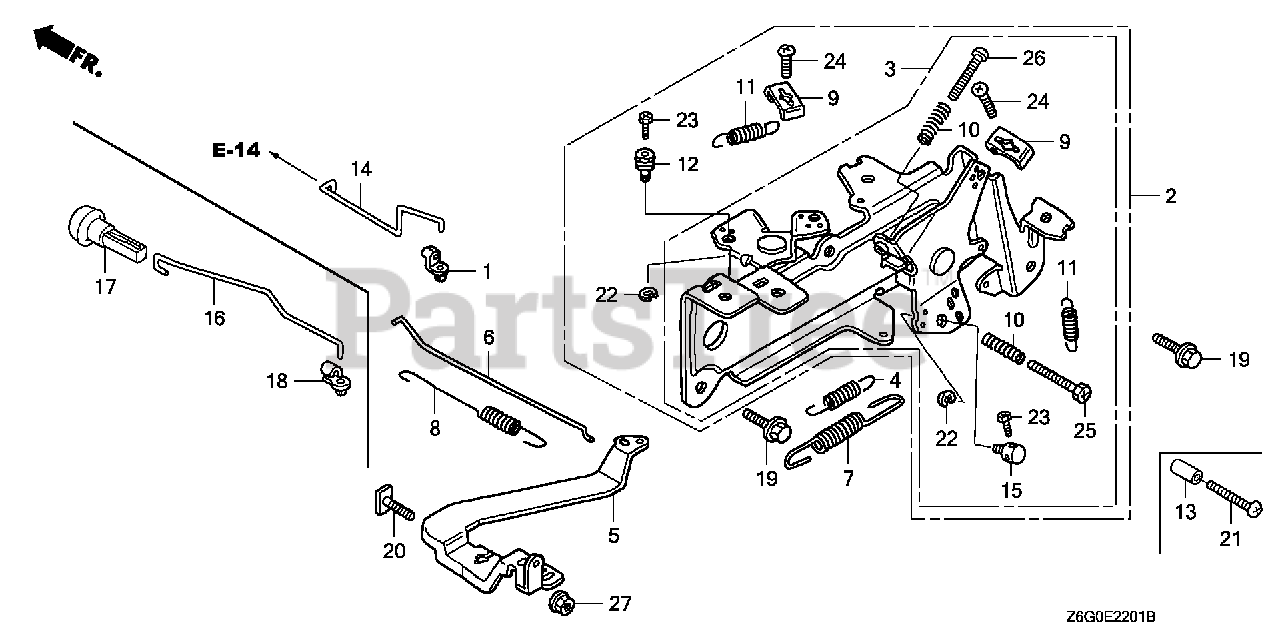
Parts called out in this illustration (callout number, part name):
1	JOINT, ROD
2	CONTROL ASSY.
4	SPRING, STARTER
5	ARM, GOVERNOR
6	ROD, GOVERNOR
7	SPRING, GOVERNOR
8	SPRING, THROTTLE RETURN
9	HOLDER, CABLE
10	SPRING, CONTROL ADJUSTING Use from Engine SN 2327377.
11	SPRING, CABLE RETURN
12	HOLDER, WIRE
14	ROD, CHOKE CONTROL
15	HOLDER, CABLE
19	BOLT, FLANGE (6X14)
20	BOLT, GOVERNOR ARM
22	CIRCLIP (5MM) Use from Engine SN 2327377.
23	BOLT, RECESSED (4X6)
24	BOLT, RECESSED (5X16)
25	BOLT, SLOT (5X25)
26	SCREW, PAN (5X25)
27	NUT, FLANGE (6MM)
